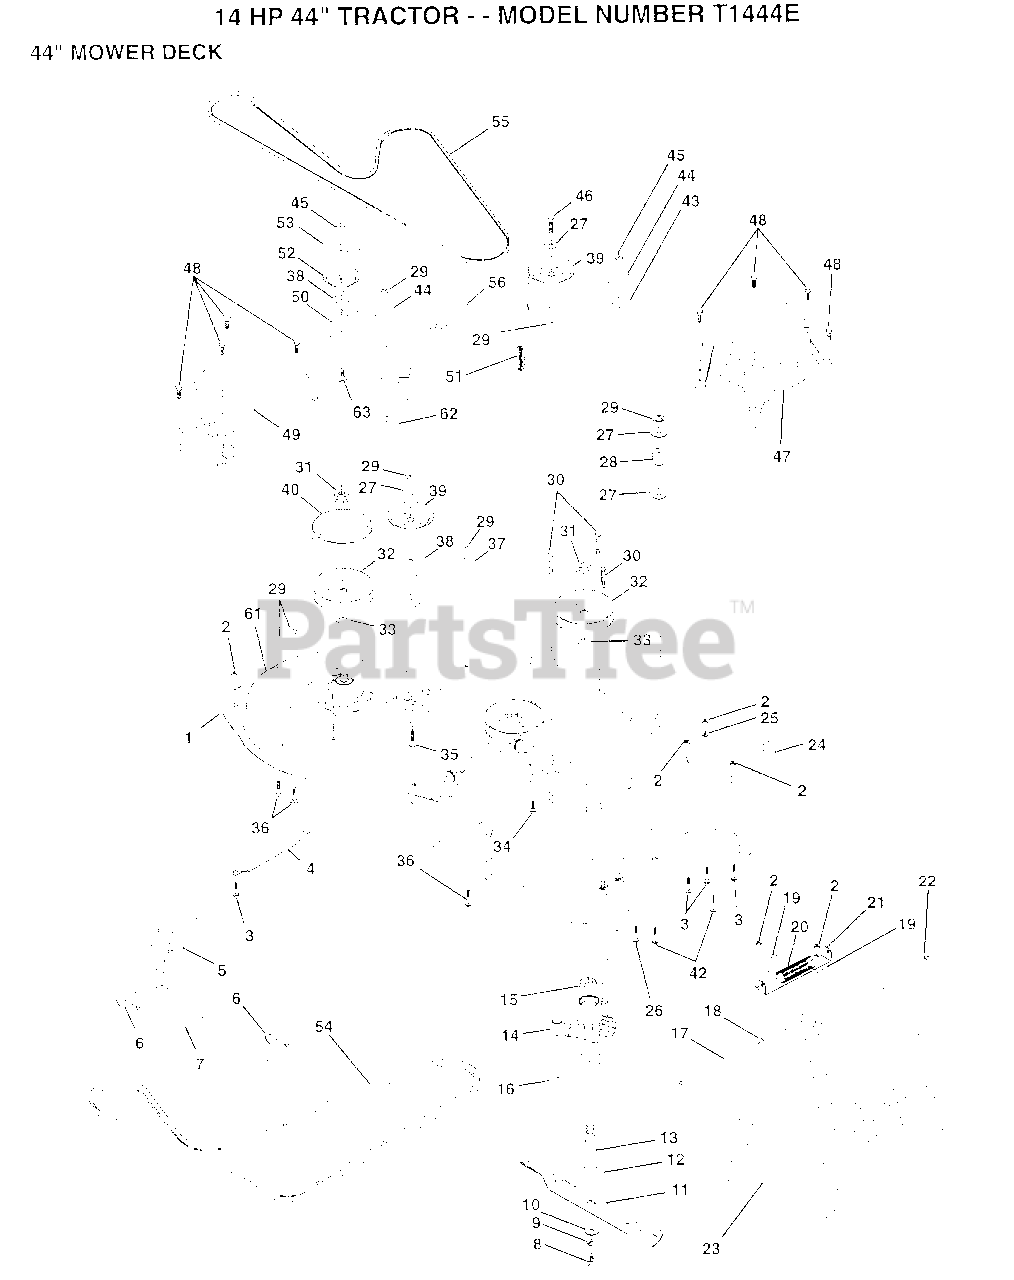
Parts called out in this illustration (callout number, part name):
1	"DECK ASM WELD44"""
2	NUT
4	RUNNER-LH M
5	BRKT.ASM.SW.44/50
8	BLADE BOLT
10	WASHER.HARD.BLADE
11	"BLADE.44"" HIPERF"
12	BEARING.BALL
13	SHAFT.ASM.W/BRNG
14	HOUSING.MAND.44.V
15	BEARING
17	ROD-HINGE T
18	WASHER
19	CAP-SLEEVE LT
20	SPRING TORSION
21	BRKT DEFLECTOR
22	NUT PUSH M
23	DEFLECTOR SHIELD
24	RUNNER.RH
25	WASHER M
26	BOLT
27	WASHER
29	NUT
33	WASHER
34	BOLT.3/8-14X1.25
35	BOLT
36	BOLT D
37	STIFFENER.ARM.IDL
39	FLAT IDLER PULLEY
40	"PULLEY.DRIVEN.44"""
42	BOLT
43	"ARM.IDLER.SEC.44"""
44	SPACER RETAINER
45	NUT
47	"COVER.MAND.RH.44"""
48	SCREW.1/4-20X5/8
49	COVER.MANDREL.LH
50	ARM.IDLER.PRIMARY
51	"SPRING.SEC.44""VEN"
52	PULLEY.IDLER.VGRO
53	SHIELD.IDLER.44.V
54	V-BELT.PRIM.78.5.
55	BELT-V.88.12.MW
56	SPRING.EXT.DECK.
61	BRACKET.GUAGE.WHL
62	HARDENED WASHER
63	BOLT.3/8-16X1.50
